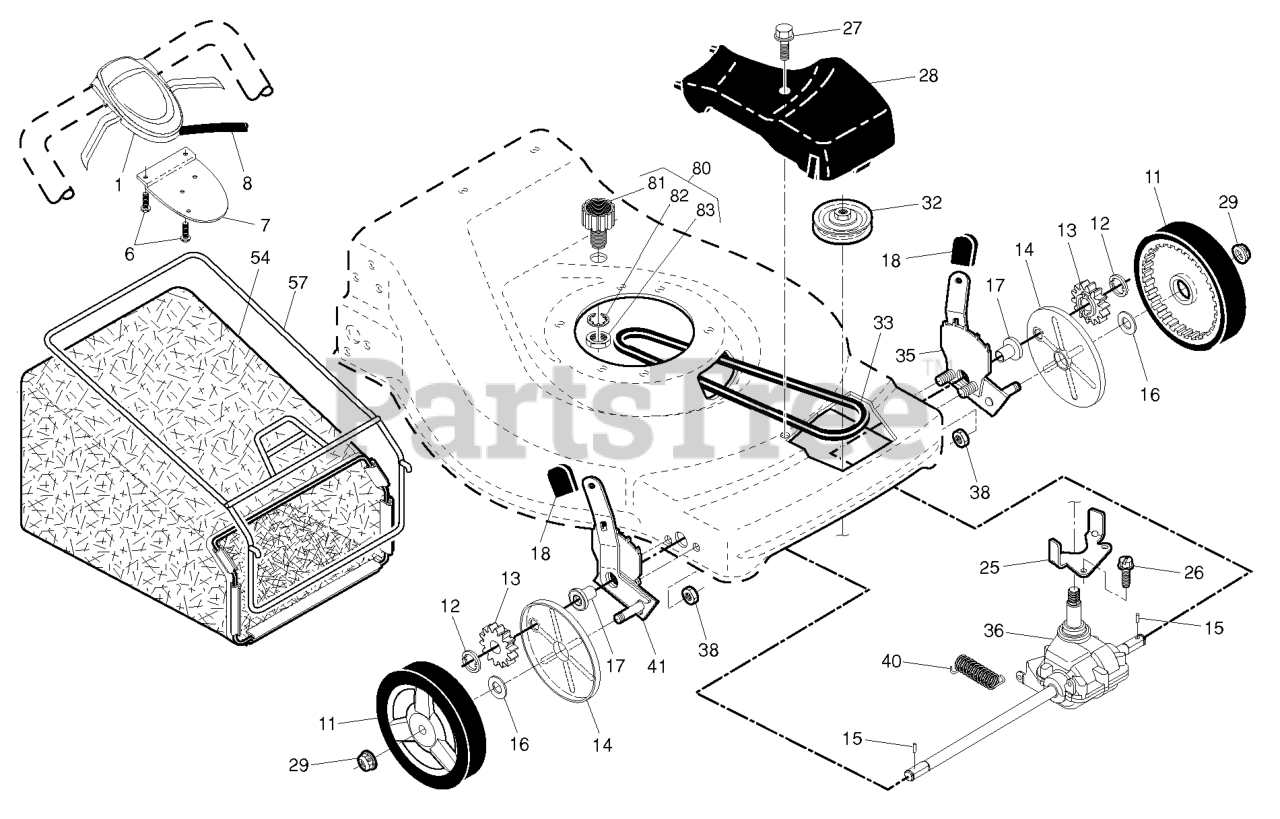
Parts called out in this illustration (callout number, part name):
1	CONTROL.AW2.22 STR.GRY.BLK
6	SCREW, PHILLIPS HEAD 10 X 5/8
7	BRACKET.DRIVE.CONTR.GEN2.BLACK
8	CABLE.DUAL.TRIGGER.FGD.TORUS
11	WHEEL.8X1.75.H3SPK.RAD3.GY.BU3
12	E-RING 7/16 RE
13	PINION.14.TEETH.FGD
14	COVER.DUST.WHEEL
15	PAWL, DRIVE
16	WASHER FLUT
17	BEARING.ASM.
18	SELECTOR KNOB
25	BRACKET.BELT.GUIDE.22+FGD.BZP
27	SCREW, HEX HD TAPPING #10-24 1
28	RP DRIVE COVER
29	NUT.HEX.FLANGE.3/8-16.LO(3 2)
32	RP PULLEY.DRIVE.EZ/VAR.SCREWON
33	BELT.DRIVE.FG
35	KIT ADJUSTER ASM.438151.
36	TRANSMISSION.22.VS.FWGD
38	LOCKNUT.NYLOC.1/4-20
41	KIT ADJUSTER ASM.438148
54	GBAG.83230247T.SIL.HUSQ.BLU
57	FRAME.GBAG.22.EZ.EMPTY.SC
80	KIT.WASH-OUT.PORT
81	FITTING, HOSE, WATER WASHOUT
82	WASHER.LOCK.INTERNAL.TOOTH
83	LOCKNUT.HEX.WITH.O-RING
